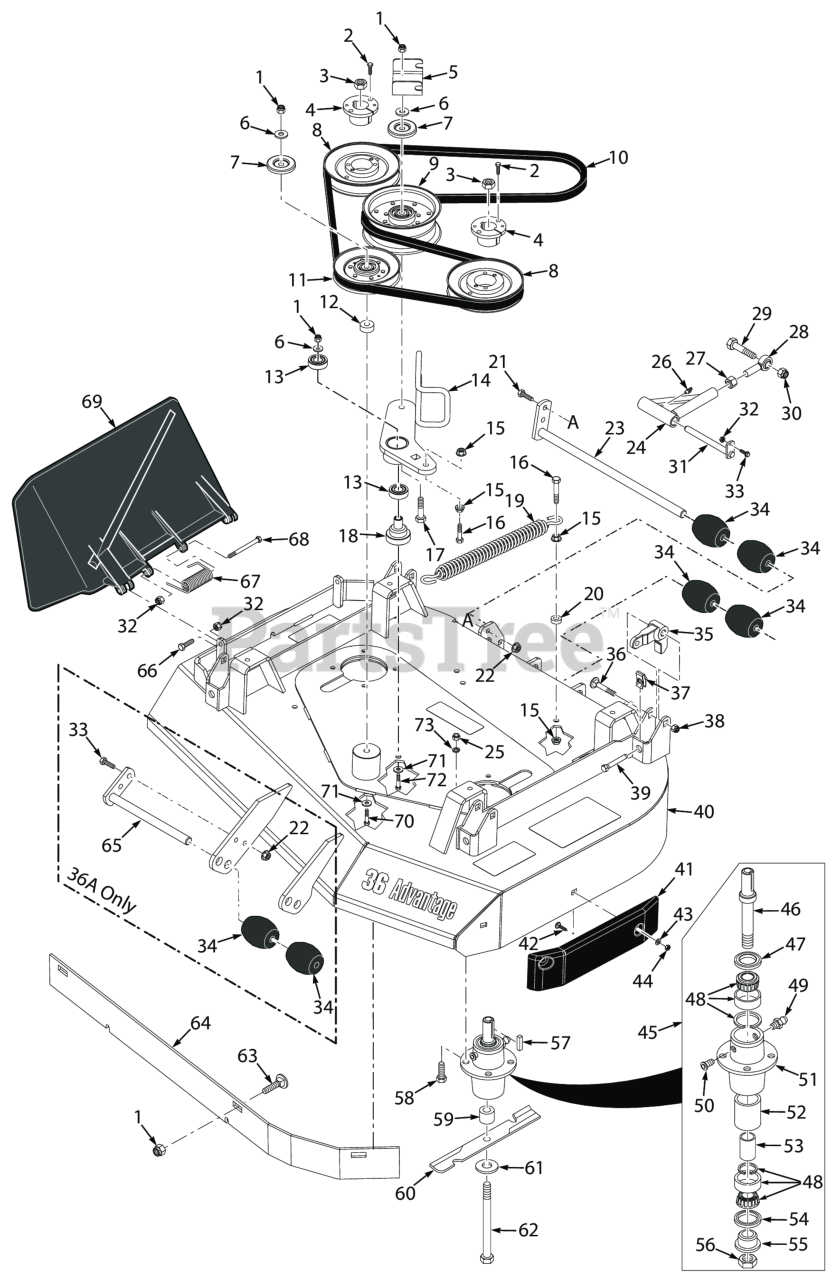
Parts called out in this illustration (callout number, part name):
1	HEX NUT, ELASTIC STOP LOCK, 3/8-16
2	Bolt, Hex Head 1/4-20 x 1" Grade 8 Black
3	Hex Locknut, Elastic Stop, 3/8-16
4	Hub, Tapered 1-1/8" Bore
5	Bracket, Belt Guide
6	Flatwasher, 3/8 (.391 x .938 x .105 HD) Grade 8
7	Quick Pin, 5/16" Dia.
8	Pulley, 5.13" Dia. - 48V
9	Pulley, Idler 5" Dia.
10	Belt, Cutter Deck
11	IDLER PULLEY, "V" GROOVE
12	SPACER, J PULL ROD
13	BEARINGS, BALL, NEUTRAL RETURN
14	Idler Arm Assembly
15	NUT, 3/8-16 SERRATED FLANGE HEX HEAD
16	Bolt, Hex Head 3/8-16 x 1-1/2" Grade 8 Black
17	Capscrew, Hex Head 3/8-16 x 3.25"
18	Pivot, Idler
19	Spring, Cutter Deck
20	SPACER, IDLER
21	Bolt, Carriage 5/16-18x1" (large frame units only)
22	Nut, Flange Head Elastic Stop 5/16-18
23	Shaft Weldment
24	Pusharm Assembly, LH
24	Pusharm Assemblly, RH
25	Lock Nut, 5/16-18 Elastic Stop Grade 8
26	Grease Fitting, 90 Degree
27	Nut, Hex Head 5/8-18 UNF
28	Rod End, 5/8" Male RH Thread
29	BOLT, HEX HEAD 5/8-11 X 4-1/2"
30	HEX LOCKNUT, ELASTIC STOP, 5/8-11
31	Shaft Weldment, Pusharm Mounting
32	HEX NUT, ELASTIC STOP LOCK, 5/16-18
33	Bolt, Heax Head 5/16-18 x 1" (48V / 52V)
34	Wheel, Anti-Scalp
35	Lever, Deck Level
36	Bolt, Carriage 7/16-14 x 2-1/4"
37	U-Nut, 3/8-16 (short)
38	HEX LOCKNUT, ELASTIC STOP, 7/16-14
39	Bolt, Hex Head 3/8-16 x 2-1/2" Soecial Lock
40	Cutter Deck w/Decals (32)
41	Pad, Deck Wear
42	Bolt, 5/16-18 x .75 RHSN Carriage
43	Flatwasher, 5/16-.344 x .688 x .065 (48V / 52V)
44	Nut, Center Lock, 5/16-18(32)
45	Spindle Assembly
46	Spindle Shaft, Tapered Brng
47	SEAL, 2.00 O.D. X 1.50 BORE
48	Tapered Bearing Set (Two Bearings W/Race)
49	GREASE FITTING, STR. 1/4-28 SELF TAP.
50	RELIEF FITTING, TAPERED BEARING SPINDLE
51	Housing, Spindle
52	Spacer, Outside, Cutter Spindle
53	SLEEVE, CUTTER SPINDLE
54	Seal, 2.00" O.D. x 1.625" Bore
55	SPINDLE BUSHING, BOTTOM
56	Nut , Spec ial 1 -1/ 1 6 - 1 8
57	Key, 1/4 x 1/4 x 2.0"
58	Bolt, Hex Head 5/16-18 x 1-3/4" Grade 8
59	Spacer, Spindle Bottom
60	Cutter Blade, 16-1/2" (48V)
61	Flatwasher, 5/8-.688 x 1-3/4 x .134 HD
62	BOLT, HEX HEAD, 5/8-11 X 9-1/2 GR.5
63	Carriage Bolt, 3/8-16 x 1.0"
64	Baffle, Flange (32)
65	Shaft Weldment, Guide Roller
66	Bolt, Hex Head 5/16-18 x 1-1/2" - Front
67	Spring, Discharge Chute
68	Bolt, 5/16-18 x 4-3/4" Hex Head
69	Discharge Chute Advantage - Small
69	Discharge Chute Assy. (CA)
70	Bolt, Hex Head 3/8-16 x 4-3/4"
71	Flatwasher, 3/8-.406 x 1-1-1/2 x 7 Gauge
72	Capscrew, Hex Head 3/8-16 x 3.25"
73	Lockwasher, 5/16 (.317 x .586 x .078) Helical Spring
